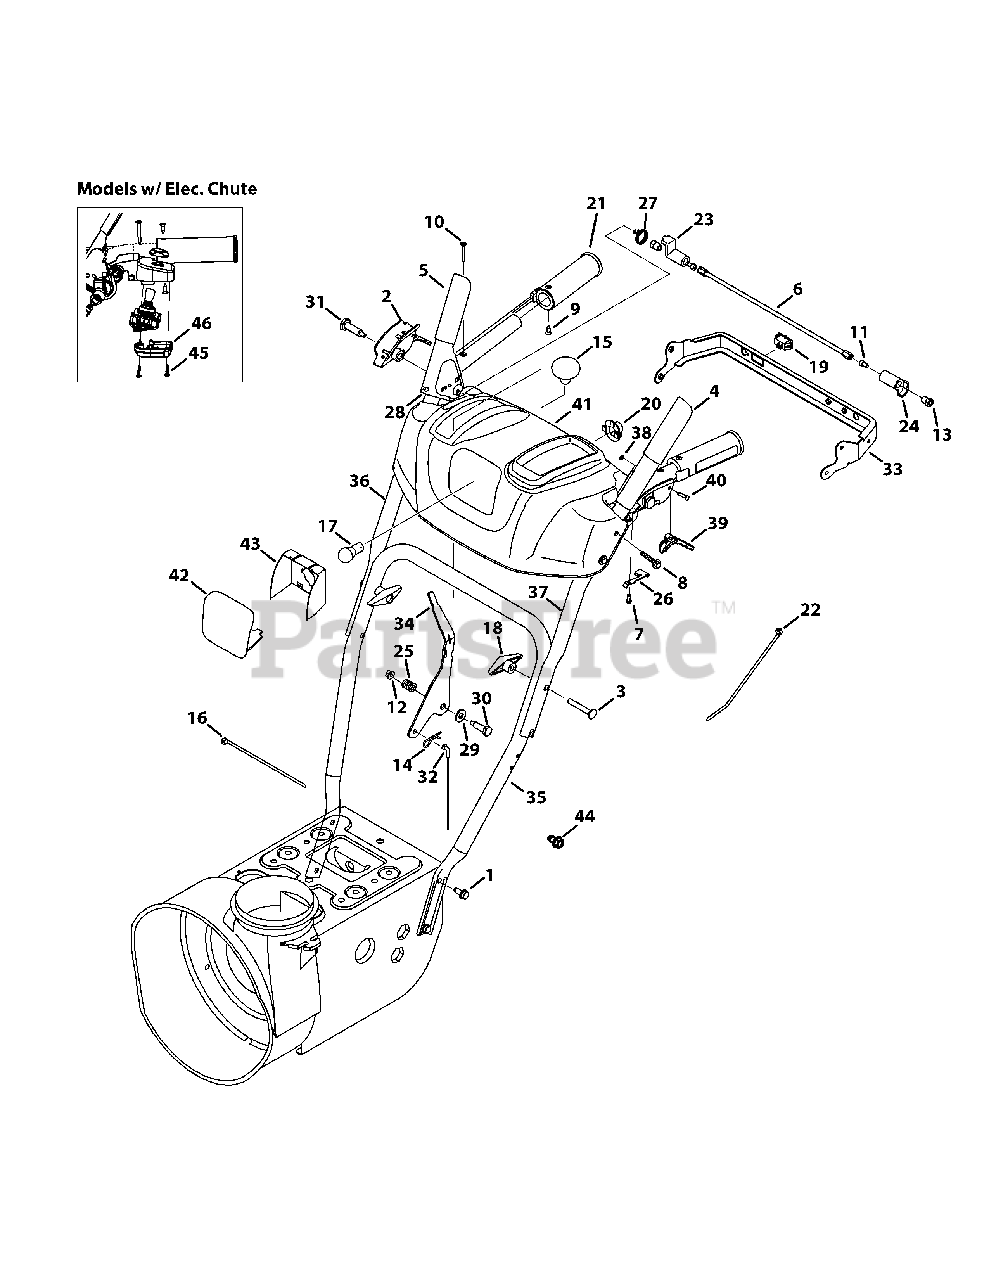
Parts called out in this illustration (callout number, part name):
1	Screw, Taptite, 5/16-18 x .750
2	Clutch Lock, RH
2	Clutch Lock, LH
3	Screw, Carriage, 5/16-18 x 2.50
4	Auger Engage, Black, LH
5	Drive Engage, Black, RH
7	Screw, Plastite, 8-16 x .50
8	Screw, Taptite, 1/4-20 x 1.625
9	Screw, 10-16 x 0.625
10	Screw, 10-24 x 1.375
11	Screw, 1/4-20 x .50
12	Nut, Flangelock, 1/4-20
13	Nut, Hex, 1/4-20
14	Click Pin, .092 x 1.64
15	Shift Knob
16	Cable Tie, 7"
18	Wing Knob, 5/16-18
19	Heated Grip Switch
20	Lamp Socket
21	Heated Grip
22	Cable Tie, Push Mount
23	Plate, Lock
24	Cam, Clutch Lock
25	Compression Spring, .39 x .60 x .88
26	Clutch Lock Spring
27	Torsion Spring, 0.8156 x .3038
28	Rubber Bumper
29	Washer, Flat, .385 x .87
30	Screw, Shield, .374 x 1.05
31	Screw, Shoulder, .437 x 1.345 x 1/4-20
32	Speed Selector Cable
33	Panel Bracket
35	Lower Handle
36	Upper RH Handle
37	Upper LH Handle
39	Steering Trigger Control, Black
40	Steering Trigger Pin, 3/16
41	Handle Panel
42	Lens Panel
43	Lens Label
44	Screw, TT, 1/4-20 x .500 (For ground wire)
45	Screw, .159 OD x .610
46	Housing Cover (Elec Chute)
